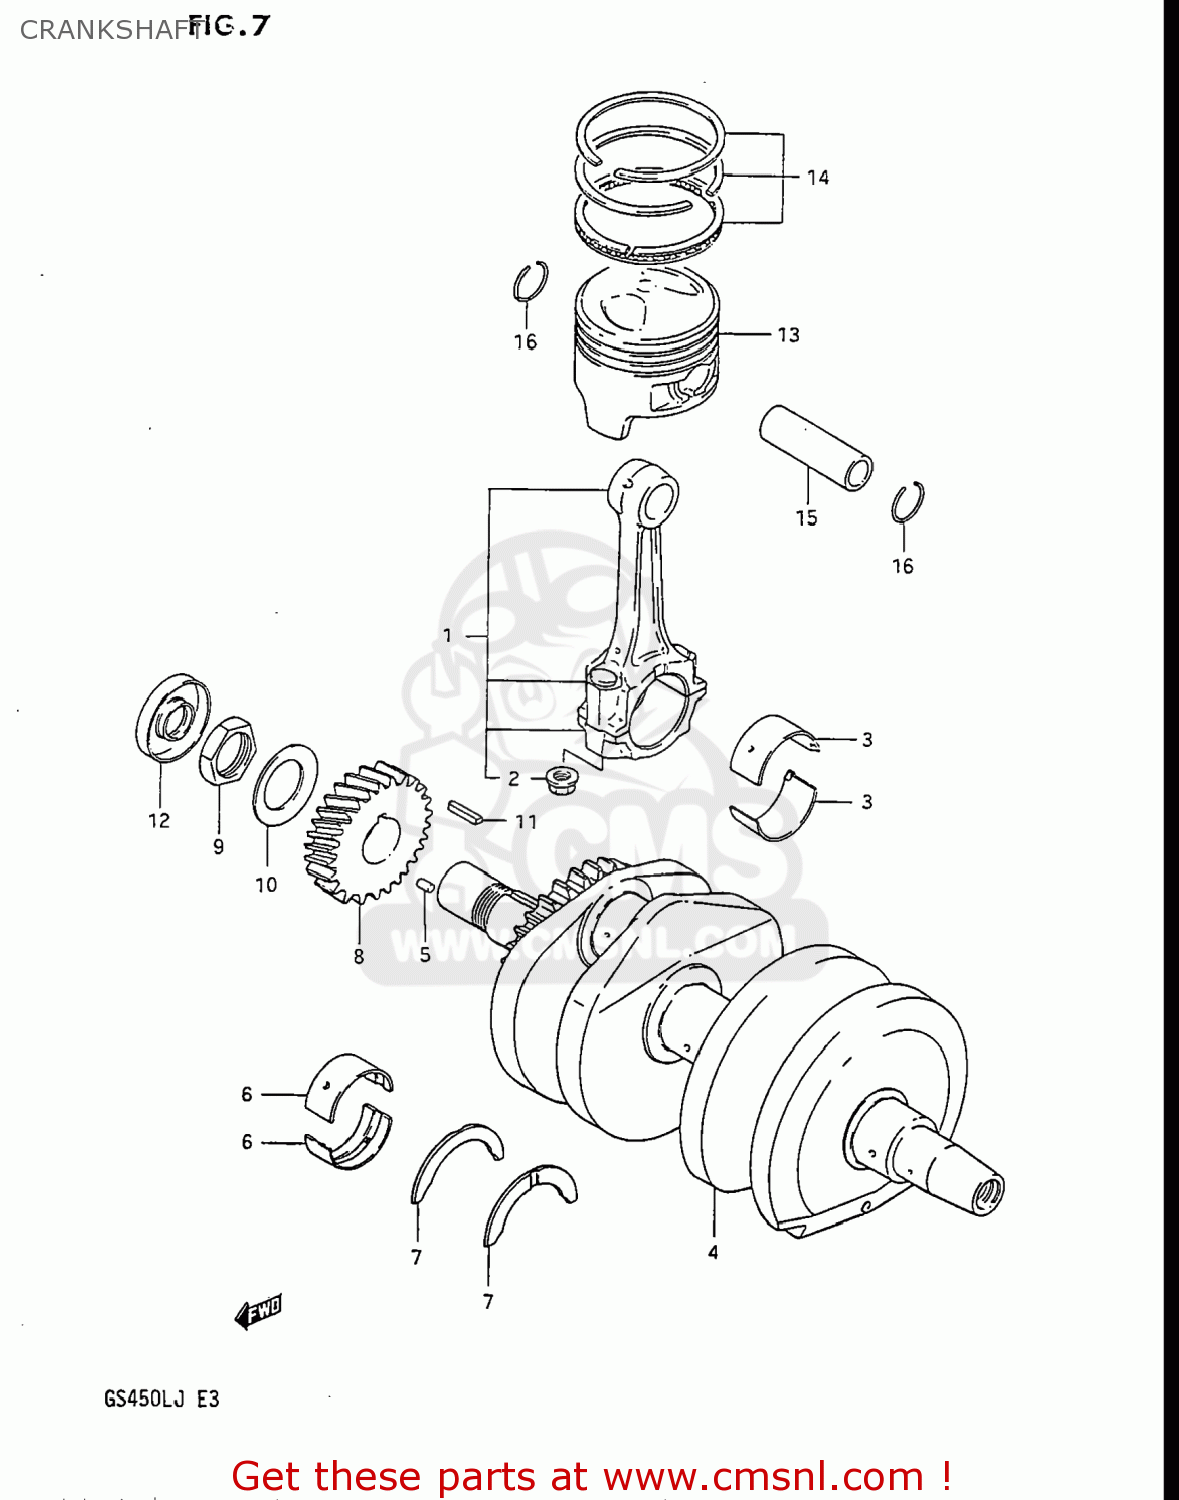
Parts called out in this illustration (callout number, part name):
1	ROD ASSEMBLY,CONNECTING
2	NUT
3	BEARING,CRANK PIN
4	CRANKSHAFT
5	PIN 3X5
6	METAL CRANKSHAFT
7	BEARING,CRANK THRUST
8	GEAR,PRIMARY DRIVE NO.28
9	NUT
10	WASHER
11	KEY
12	SEAL,OIL(22X40X8)
13	PISTON
14	RING SET,PISTON
15	PIN,PISTON (18MM)
16	CIRCLIP
